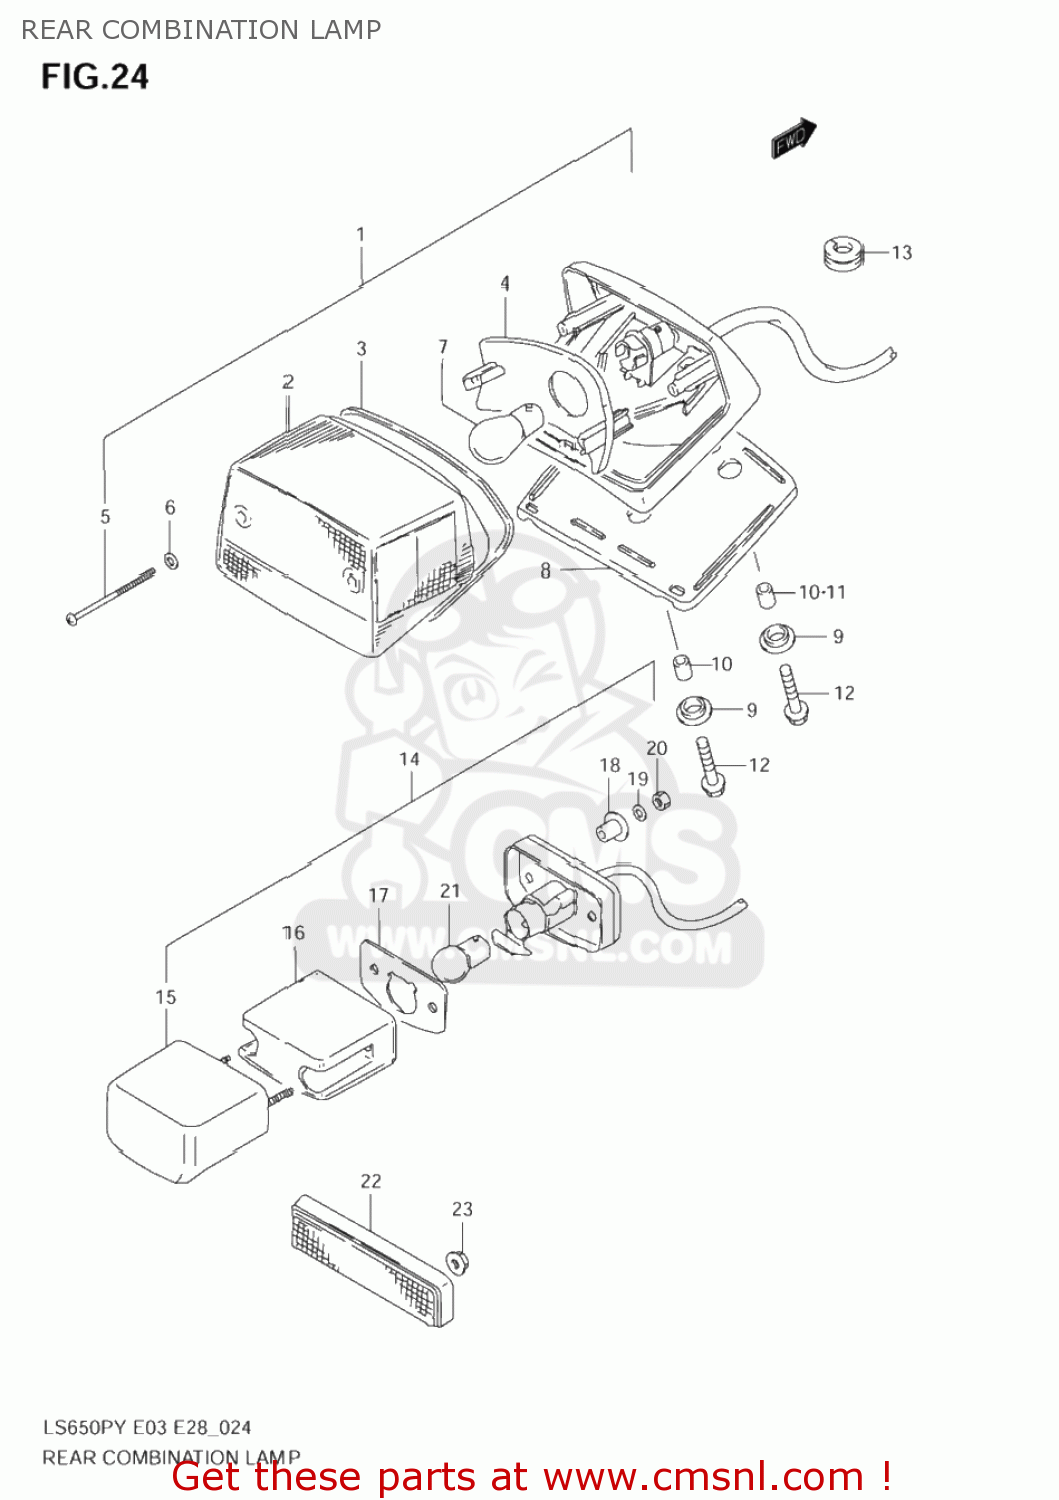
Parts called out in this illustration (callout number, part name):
1	LAMP ASSY,RR COMBINATION
2	LENS
3	GASKET (NAS)
4	REFLECTOR
5	SCREW
6	GASKET (NAS)
7	BULB(12V21/5W,BF141-49642A)
8	CUSHION
9	CUSHION
10	SPACER
11	SPACER
12	BOLT(6X25)
13	GROMMET
14	LAMP ASSY,LICENSE
15	COVER,LICENSE LAMP
16	LENS
17	GASKET,LICENSE LAMP (NAS)
18	SPACER
19	WASHER,LOCK
20	NUT
21	BULB(12V8W)
22	REFLEX REFLECTOR ASSY,RR
23	NUT
